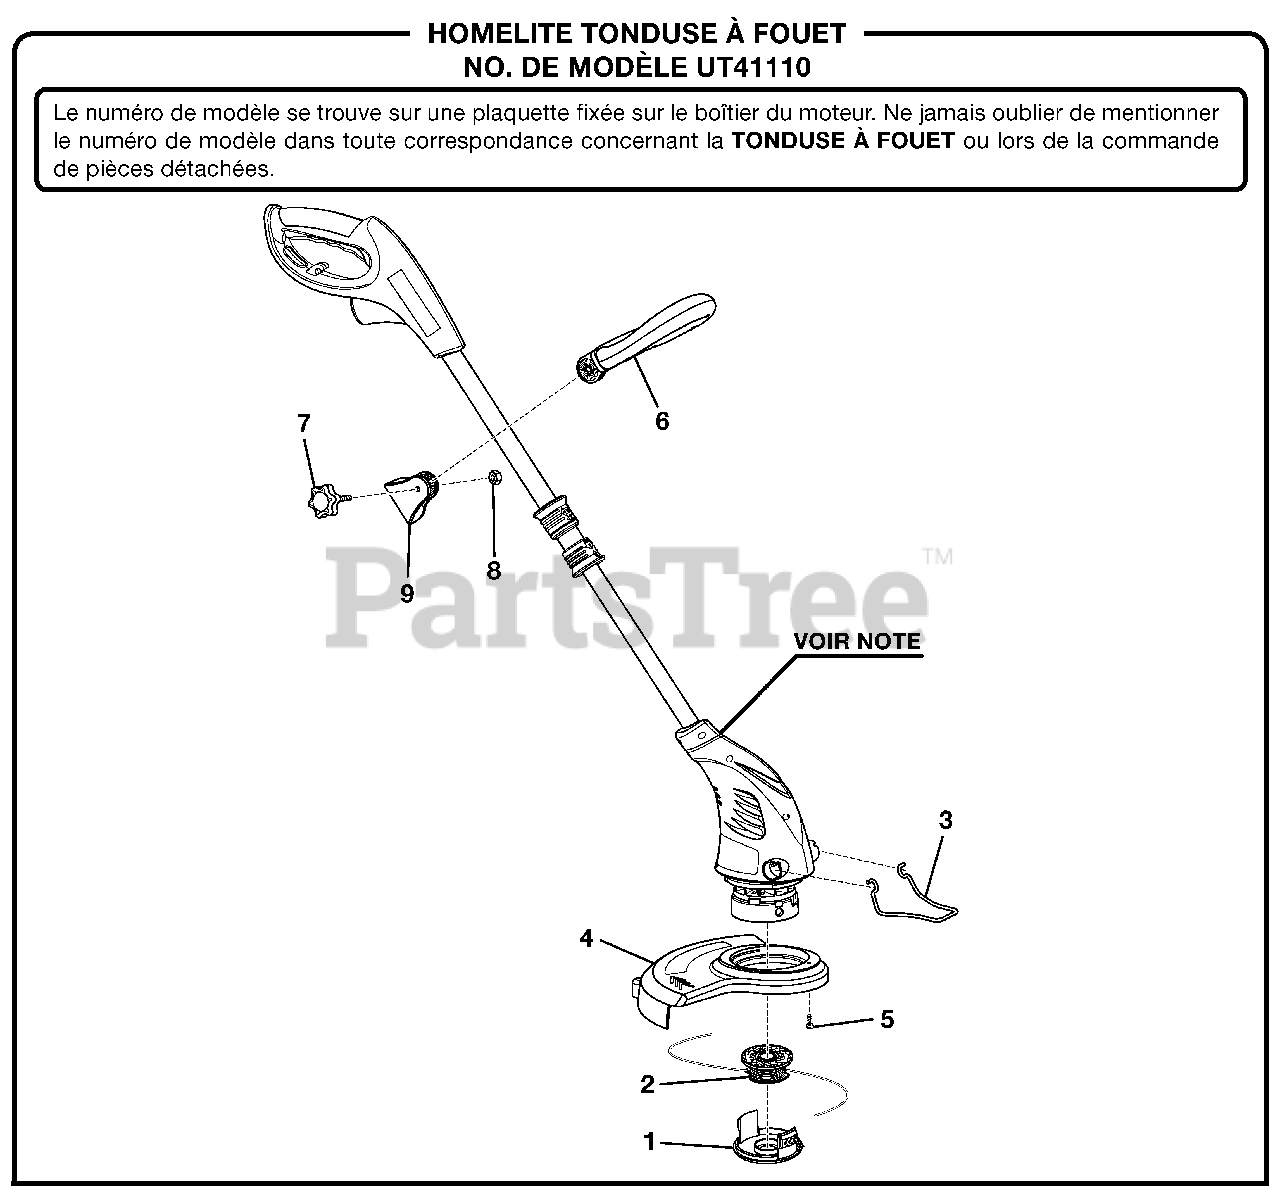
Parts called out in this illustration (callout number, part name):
1	Creux De bobine
3	Garant De Deligneuse
4	Protecteur
5	Vis
6	Poignee Avant
7	Vis De Bouton
8	Ecrou Hex
